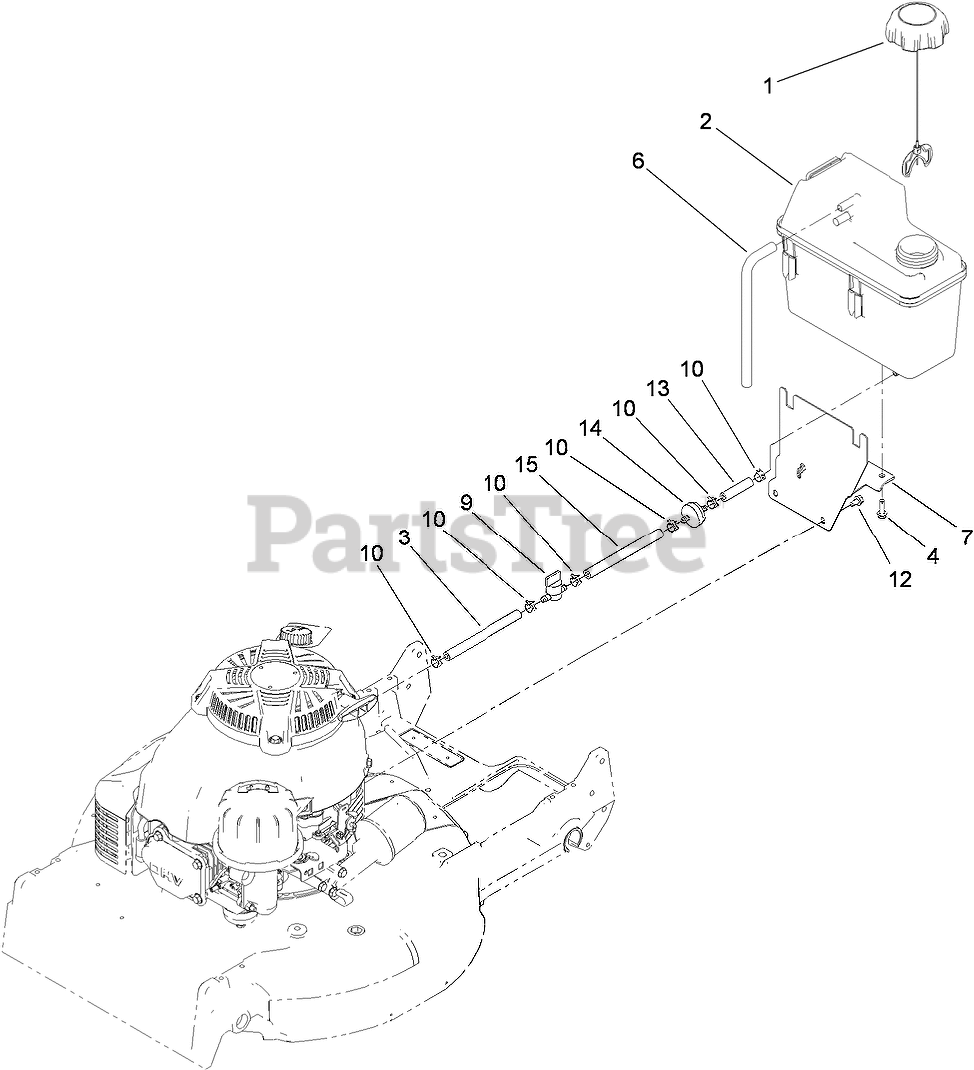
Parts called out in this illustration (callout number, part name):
1	CAP-RATCHET, TETHERED
2	TANK-FUEL
3	HOSE-FUEL
4	SCREW-HWH
6	HOSE-VENT, CANISTER
7	MOUNT-TANK
9	VALVE-FUEL
10	CLAMP-HOSE
12	SCREW-HWH
13	HOSE-FUEL
14	FILTER-FUEL
15	HOSE-FUEL
